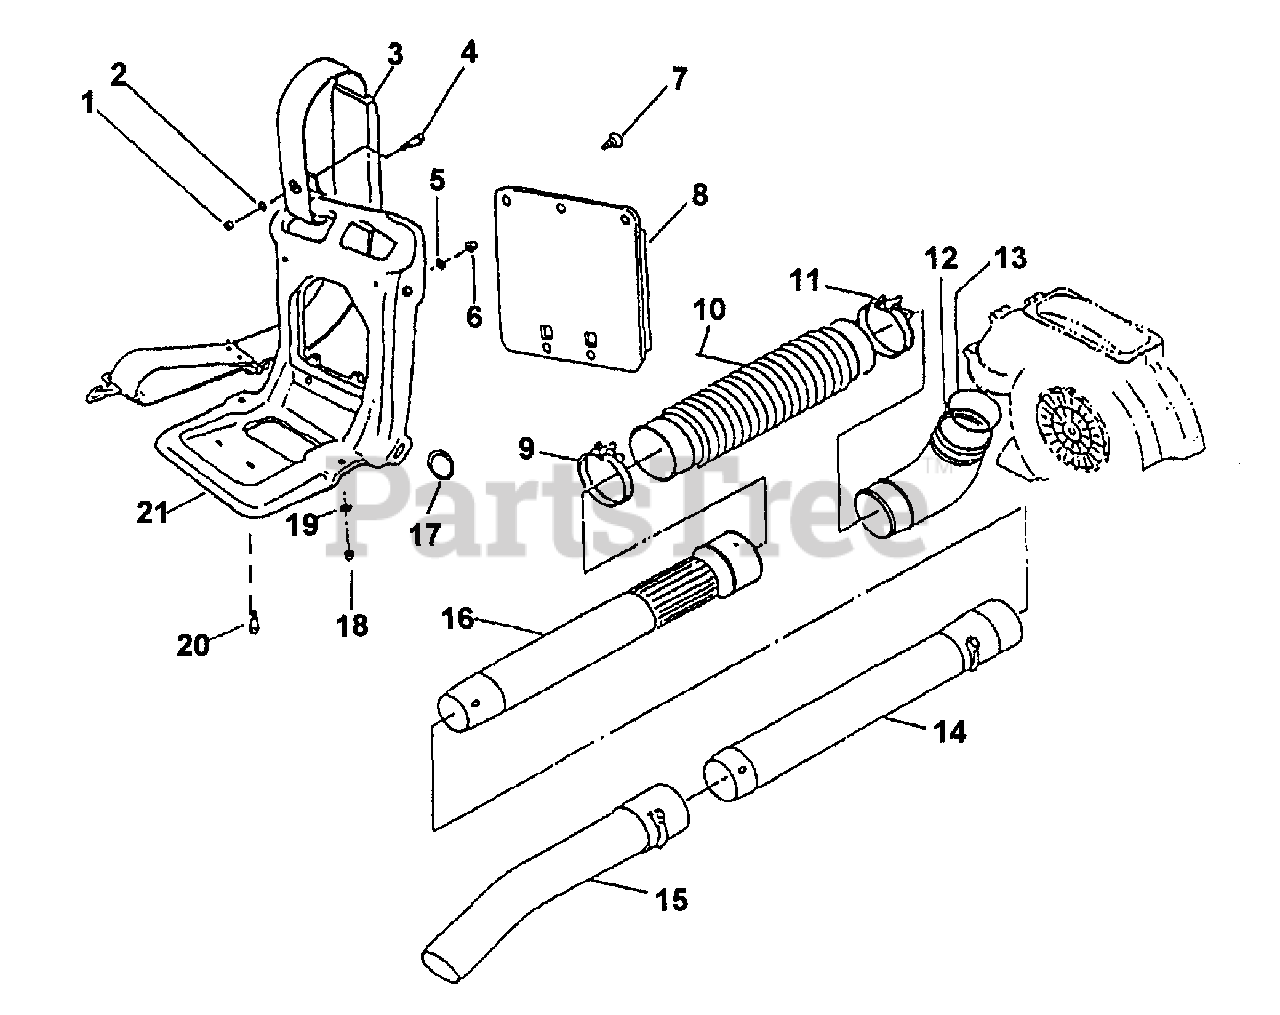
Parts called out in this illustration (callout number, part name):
1	NUT
3	SHOULDER STRAP
4	SCREW
6	NUT
8	KNAPSACK PAD
9	HOSE BAND
10	FLEXIBLE TUBE
11	HOSE BAND
12	ELBOW TUBE
14	MIDDLE TUBE
15	BENT TUBE
16	BASE TUBE
18	NUT
20	SCREW
21	FRAME, KNAPSACK
